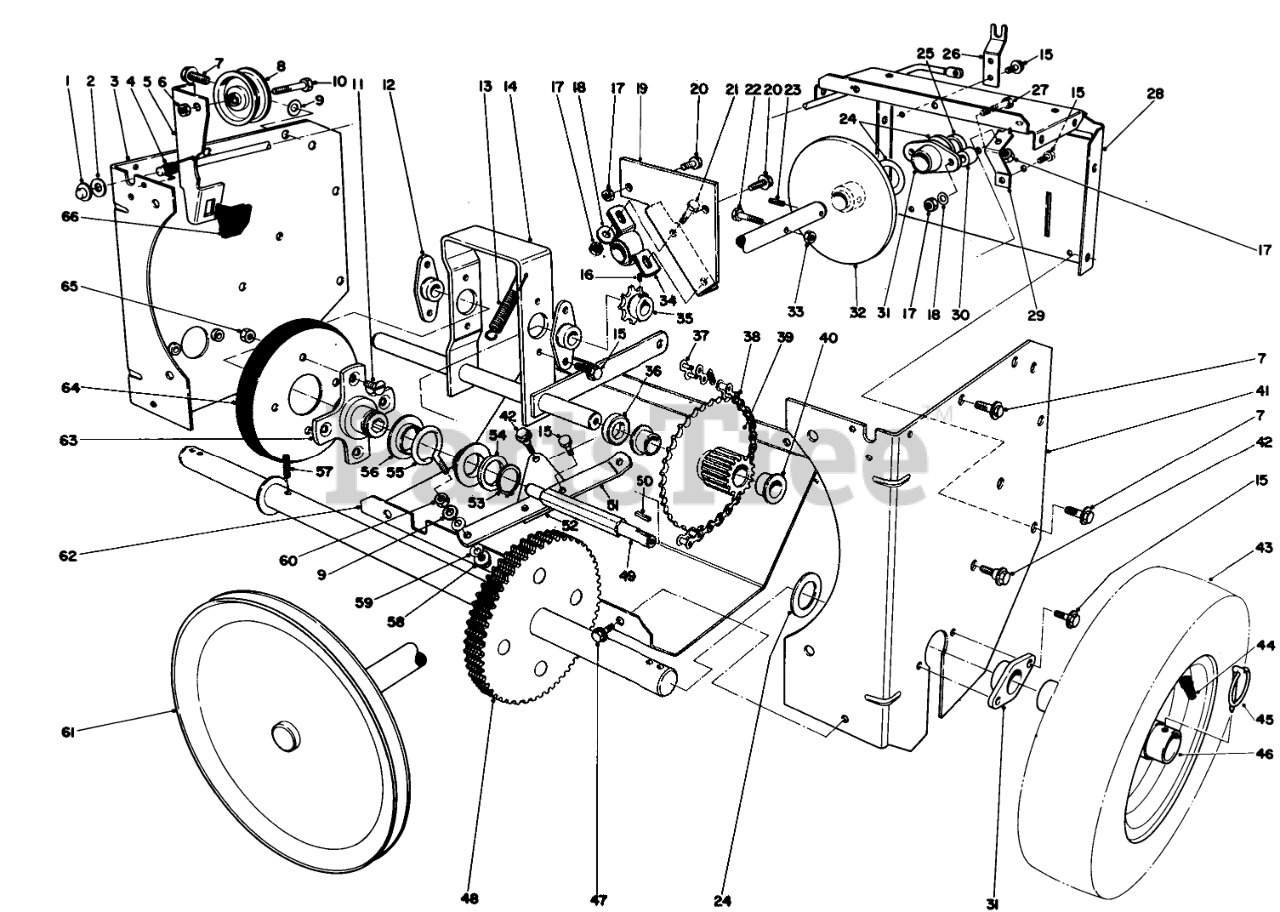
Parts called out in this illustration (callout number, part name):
1	PUSH NUT
2	WASHER-FLAT
3	RH TRACT SIDE PLT R
4	TORSION CLUTCH SPRING
5	Clutch Rod (Incl. Ref. #66)
6	NUT-LOCK, NI
7	SCREW-HWHTF
8	PULLEY-IDLER
9	WASHER-FLAT
10	SCREW-HH
11	5/16-18X5/8 FLT HD MS
12	BEARING-WHEEL, FRICTION
13	TENSION SPRING
14	PIVOT SHAFT WA B
15	SCREW-HWHTF
16	SCREW-HSH
17	NUT-LOCK, NI
18	WASHER-PLAIN
19	SHAFT SUPT BRKT B
20	SCREW-HH
21	SCREW-HH
22	SCREW-HH
23	PIN-ROLL, SLOTTED
24	WASHER
25	DRIVE SHAFT SPACER
26	CLUTCH ROD SUPPORT
27	SCREW-HH
28	CENTER FRAME R
29	PIVOT BRACKET
30	BRG STANDOFF
31	AXLE BEARING
32	FRICTION PLT WA
33	NUT-LOCK, CONE
34	PILLOW BLOCK BRG
35	SPROCKET
36	COSHAFT SPACER
37	LINK-CONNECTING
38	ROLLER-CHAIN
39	Gear & Bushing (Incl. Ref. #40)
40	BUSHING
41	LH TRACT SIDE PLT R
42	SHOULDER SCREW
44	TUBE-INNER
45	PIN-LYNCH
46	Wheel
47	SCREW-HWH
48	AXLE & GEAR WA
49	FRICTION WHL SHAFT
51	SHIFT LINKAGE
52	PIVOT PLATE
53	RING-RETAINING
54	WASHER-THRUST
55	SLIDER RING COLLAR
56	SLIDER RING
57	PIN-ROLL, SLOTTED
58	NUT-LOCK, FLANGE
59	WASHER-SPRING
60	NUT-LOCK
61	PULLEY/SHFT WA
62	LOWER SHIELD R
63	TRACTION DISC HUB
64	FRICTION WHEEL
65	NUT-LOCK, NI
66	Brake Pad
